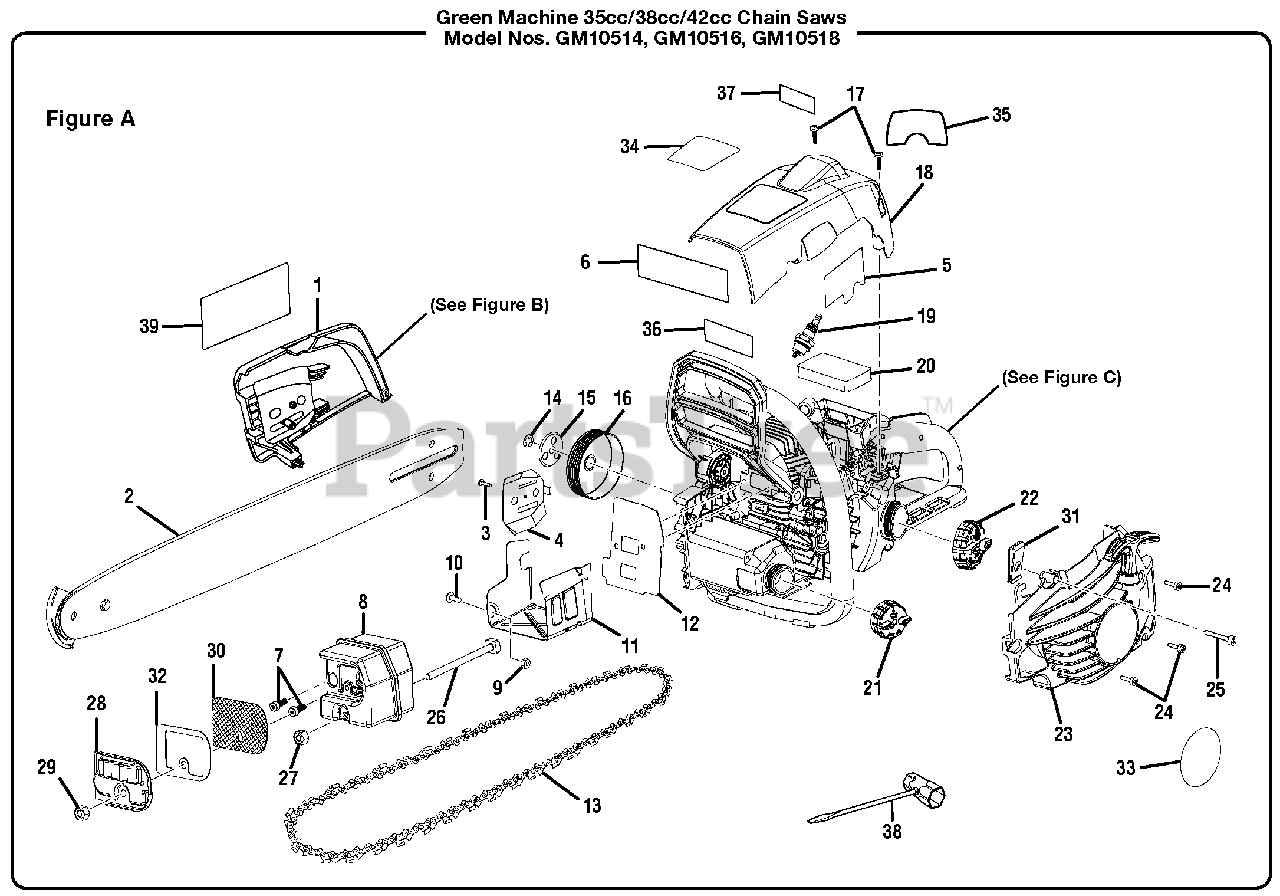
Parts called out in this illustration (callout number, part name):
1	Chain Cover Assembly
2	Guide Bar with SAFE-T-TIP: GM10514 - 14 in
3	Screw (6-19 x 1/2 in.)
4	Inner Guide Plate
5	Heat Shield Tape
6	Heat Shield Tape
7	Screw (1/4-20 x 5/8 in.)
8	Muffler Assembly
9	Lock Nut (10-24)
10	Screw (10-24 x 5/8 in.)
11	Heat Shield
12	Muffler Gasket
13	Chain (3/8 in.): GM10514 - 52 link, 14 in
14	E-Clip
15	Clutch Washer
16	Sprocket Drum and Bearing Assembly (.375 chain)
17	Screw (10-16 x 16 mm)
18	Cylinder Cover
19	Spark Plug (Champion RCJ4)
20	Air Filter
21	Oil Cap Assembly
22	Fuel Cap Assembly
23	Starter Cover Assembly
24	Screw (M4 x 17 mm)
25	Screw (#10-16 x 24 mm, T25 Torx)
26	Screw (#10-32 x 2.8 in.)
27	Nut (#10-32)
28	Exhaust Cover
29	Nut, Muffler (M5)
32	Exhaust Cover Gasket
33	Starter Cover Labels: GM10514 - 35cc
34	Warning Labels: GM10514 - 35cc
35	Starting Instruction Label
36	Chain Brake Label
37	Warning Label (Combustion)
38	Combination Wrench
39	Clutch Cover Labels: GM10514 - 35cc
